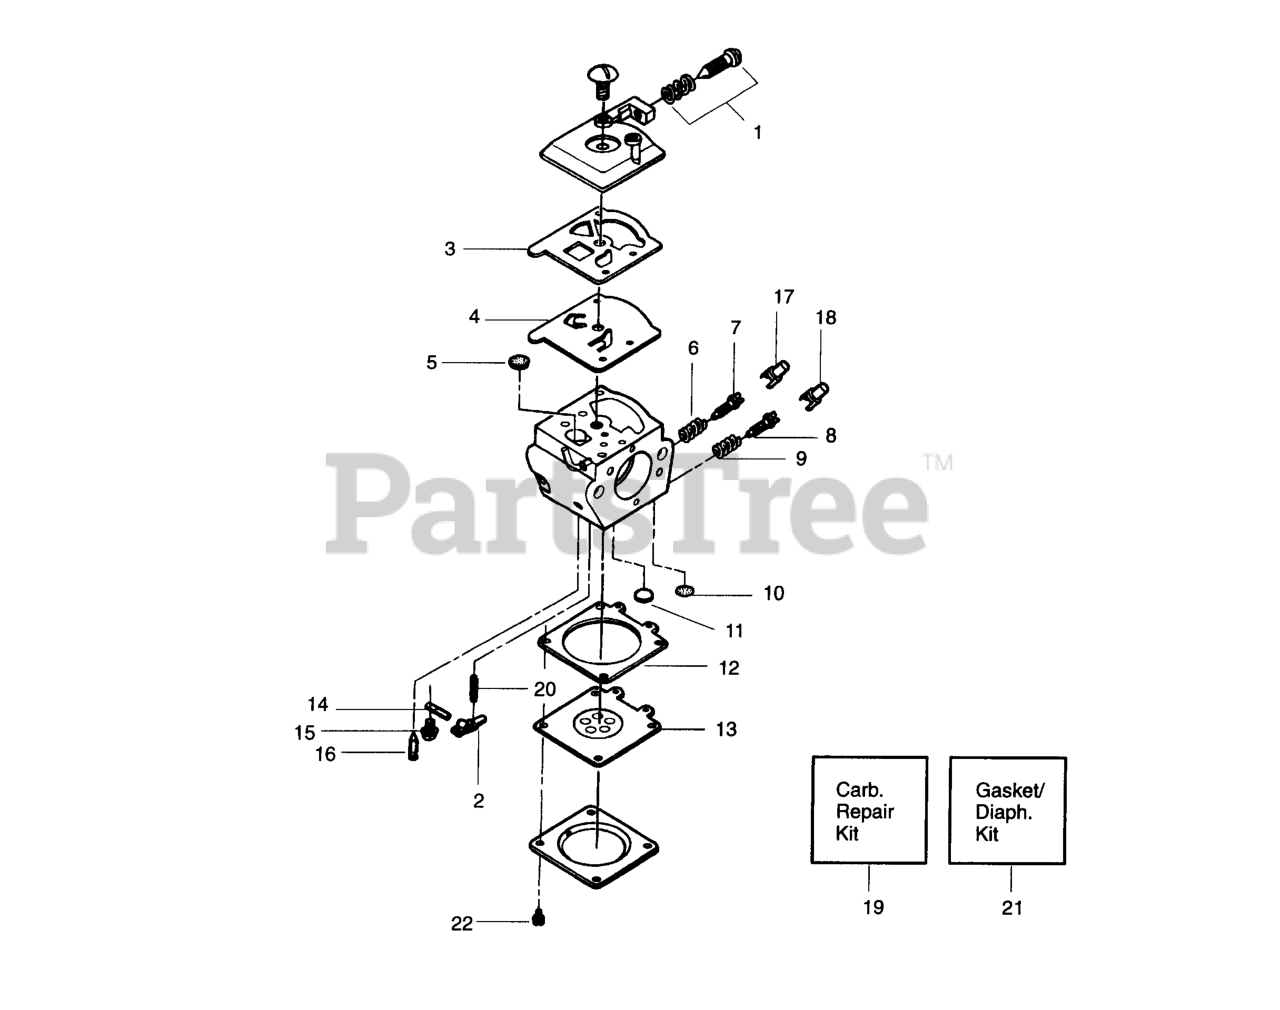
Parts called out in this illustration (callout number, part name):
1	Idle Adv. Screw Kit
2	LEVER
3	GASKET-FUEL PUMP
4	DIAP FUEL PUMP
5	FILTER SCREEN
6	NEEDLE SPRING
7	LOW SPEED NEEDLE
8	Needle High Speed
9	NEEDLE SPRING
10	Welch Plug (5/16)
12	METERING DIA GASKET
13	DIAPHRAGM
14	PIN
16	INLET NEEDLEVALVE
17	LIMITER CAP (HIGH-RED)
18	LIMITER CAP (LOW-BLUE)
19	Carburetor Repair Kit
20	SPRING-METERING LEVER
21	GASKET SET (WT202)
22	SCREW, MOTOR COVER
